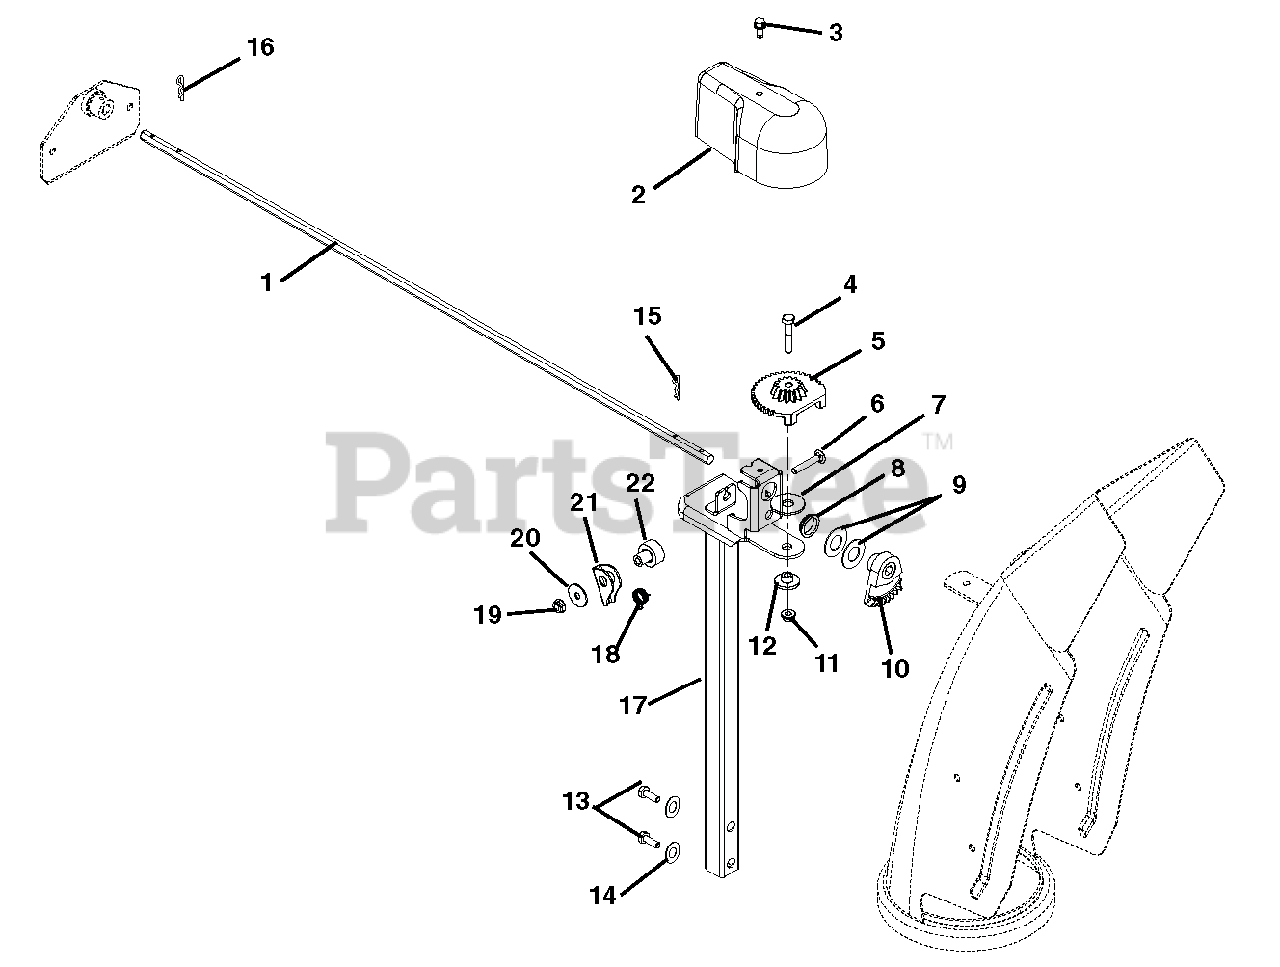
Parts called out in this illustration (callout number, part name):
1	ROD, CHUTE ROTATION-HEX
2	COVER, CHUTE GEAR
3	SCR-TAP .25-20X.50 HWH TR YWZ
4	@BLT-HEX .25-20X1.50 GR5 YWZC
5	GEAR, CHUTE
6	@BLT-RDHDSQNK .25-20X1.50 G5YZ
7	WSHR-FLT-NYL .515X1.375X.093
8	BUSHING, POLYLINER-.75 SNAPIN
9	WSHR-FL-STL.754X1.125X.062YWZC
10	GEAR, CHUTE-ACTUATION
11	@NUT-LK-TOP-FLG .25-20 YWZC
12	BSHG-FLG .265X.477X.375X1.00
13	@BLT-HEX .38-16X1.75 GR5 YWZC
14	@WSHR-LK .38X.094 REG YWZC
15	CLIP, SPRING
16	HAIRPIN, #7 CLIP .094X2.31 YWZ
17	PEDESTAL, CHUTE-QUICK STICK
18	SG-TORS
19	@NUT-LK-TOP-FLG .25-20 YWZC
20	WSHR-FL-STL .281X1.000X.063
21	ARM, LOCKING
22	BUSHING, LOCK ARM
